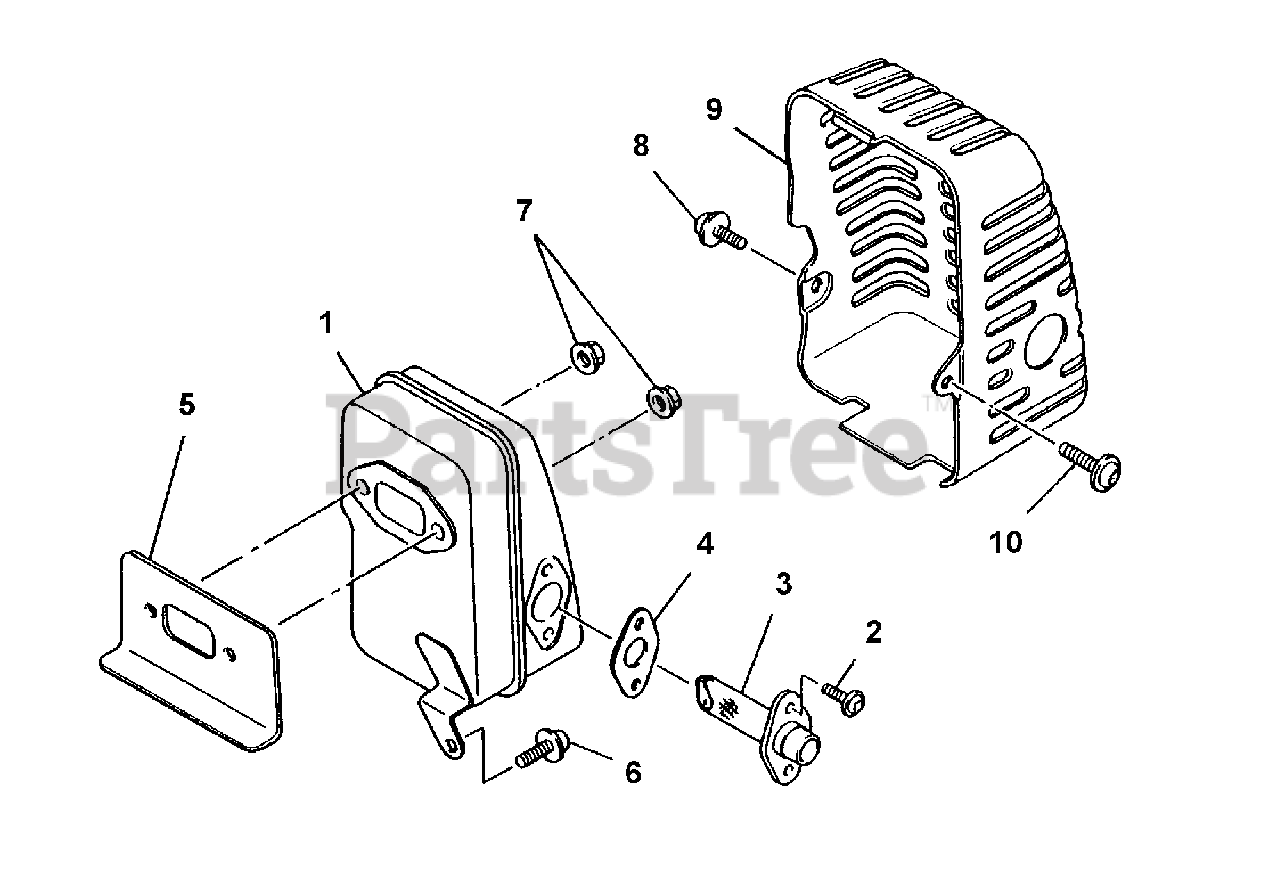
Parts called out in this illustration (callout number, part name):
1	Muffler Assembly
2	Screw & Washer
3	Tail Pipe
4	Gasket, Tail Pipe
5	Gasket, Muffler
6	Screw & Washer
7	Nut, Flange
8	Screw & Washer
9	Cover, Muffler
10	Screw & Washer
